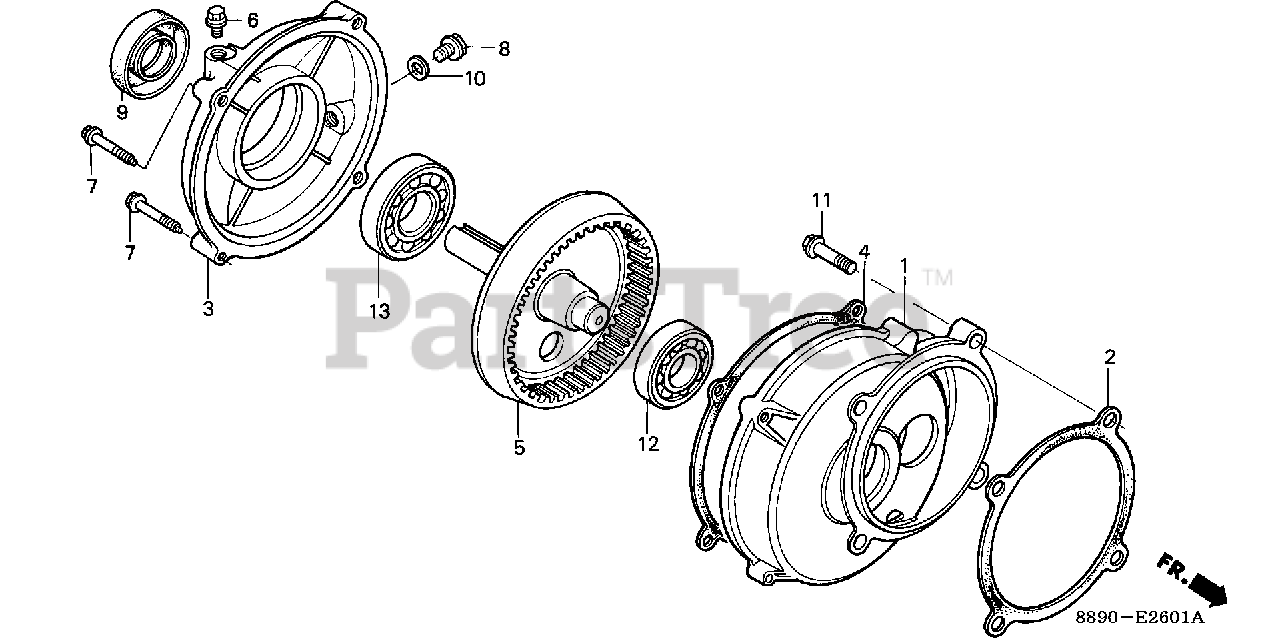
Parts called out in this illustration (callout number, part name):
1	CASE, REDUCTION
2	GASKET, REDUCTION CASE (NOT AVAILABLE)
3	COVER, REDUCTION
4	GASKET, REDUCTION COVER
4	GASKET, REDUCTION COVER (NOT AVAILABLE)
5	SHAFT, P.T.O. (NOT AVAILABLE)
6	BOLT, BREATHING
7	BOLT, FLANGE (6X32) (CT200)
7	BOLT, FLANGE (8X35)
8	BOLT, DRAIN PLUG (12X15)
9	OIL SEAL (30X46X8)
10	WASHER, DRAIN PLUG (12MM)
11	BOLT, FLANGE (8X32)
12	BEARING, RADIAL BALL (6204)
13	BEARING, RADIAL BALL (6206)
